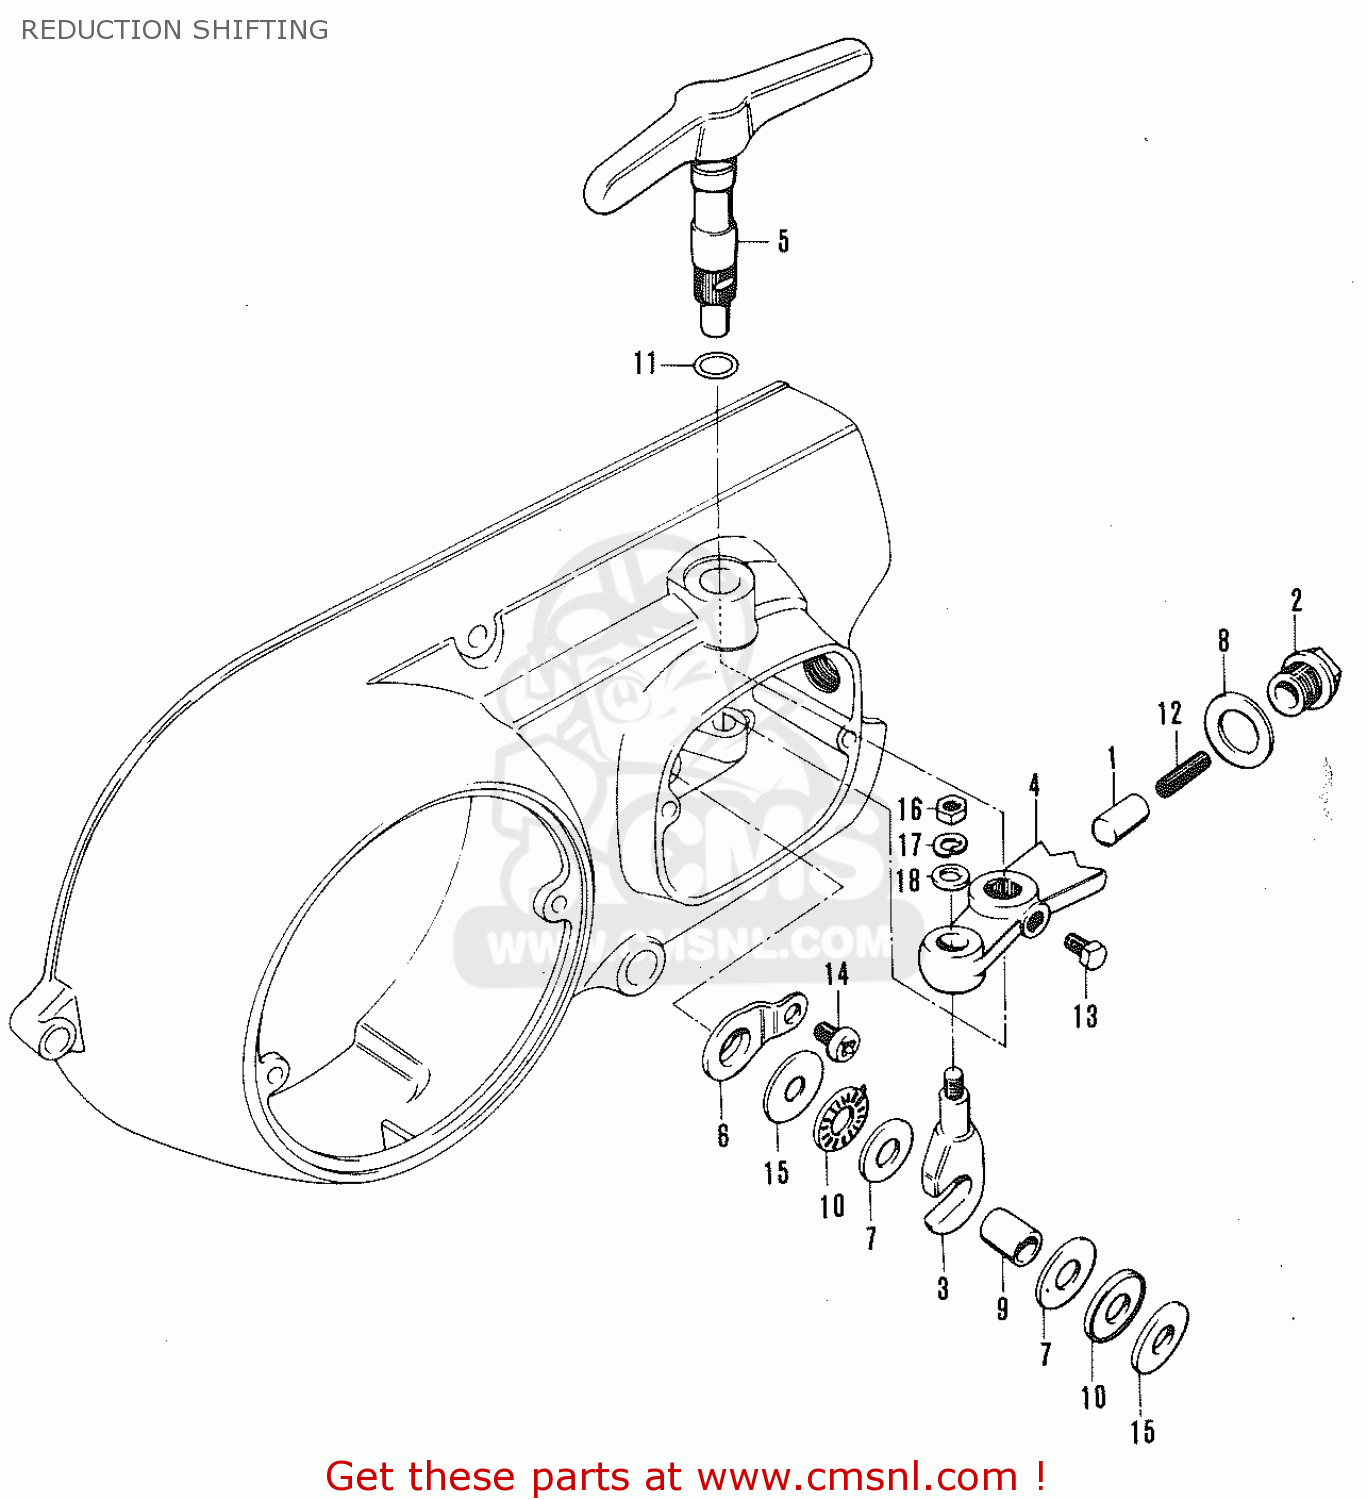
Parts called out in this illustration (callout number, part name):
1	STOPPER,GEAR SHIFTING
2	HOLDER,SHIFTING CAM STOPPER
3	REDUCTION SHIFTING ARM PIN
4	ARM,REDUCTION SHAFT
5	REDUCTION SHIFTING LEVER
6	REDUCTION ROD DUST SEAL
7	WASHER(10.1X21.4X0.8)
8	WASHER (14.2X22X1)
9	SPACER(6X10X12.2)
10	BEARING(10X22X2.8)
11	O RING(D:1.3,ID:9.6)
12	SPRING
13	BOLT 5X16
14	SCREW
15	WASHER
16	NUT
17	LOCK WASHER
18	WASHER
